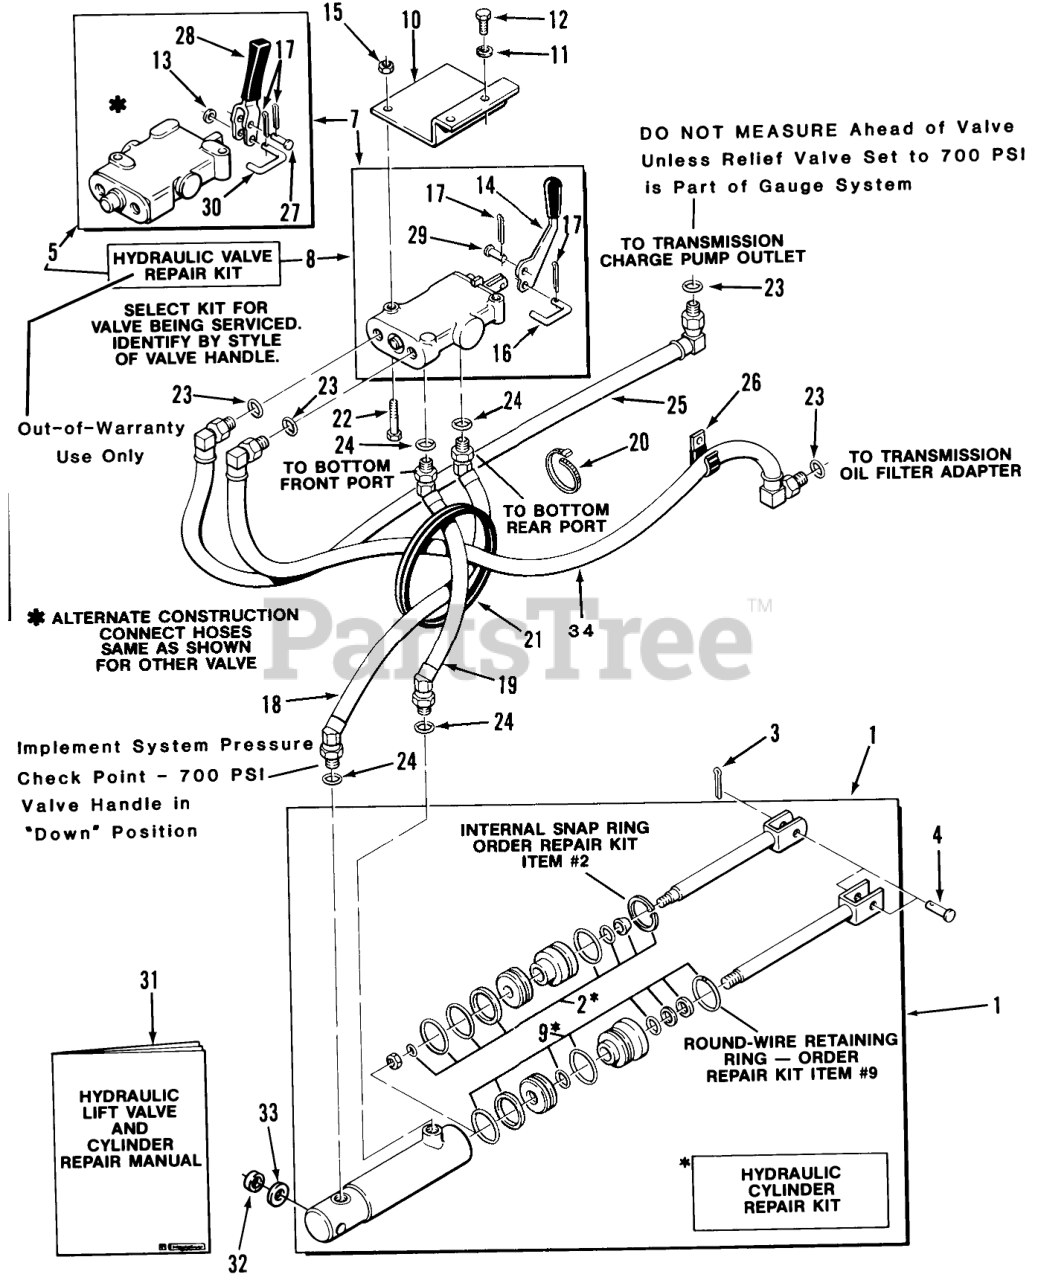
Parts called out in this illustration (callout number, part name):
1	CYLINDER
2	S/A O-RING&GASKET AS
4	CLEVIS PIN
5	S.A. Valve Repair Kit
7	Hydraulic Valve
8	S/A 110068 VALVE
9	S/A 108872 HYD CYL
10	ASSY VALVE SUPPOR B
11	Lockwasher
12	Bolt
13	WASHER
14	VALVE HANDLE
15	Nut
16	C-HOOK
17	Cotter Pin
18	Hose ASM-Hydraulic
19	Hose ASM-Hydraulic
20	PLASTIC TIE
21	GROMMET
22	Screw-Hex. Hd.
23	0-Ring
24	O RING
25	ASSY HOSE HYDRAULIC
26	CLIP
27	CLEVIS PIN
28	Valve Handle
29	Pin
30	Link Wire
31	Repair Manual
32	Spacer
33	WASHER
34	ASSY HYD HOSE
